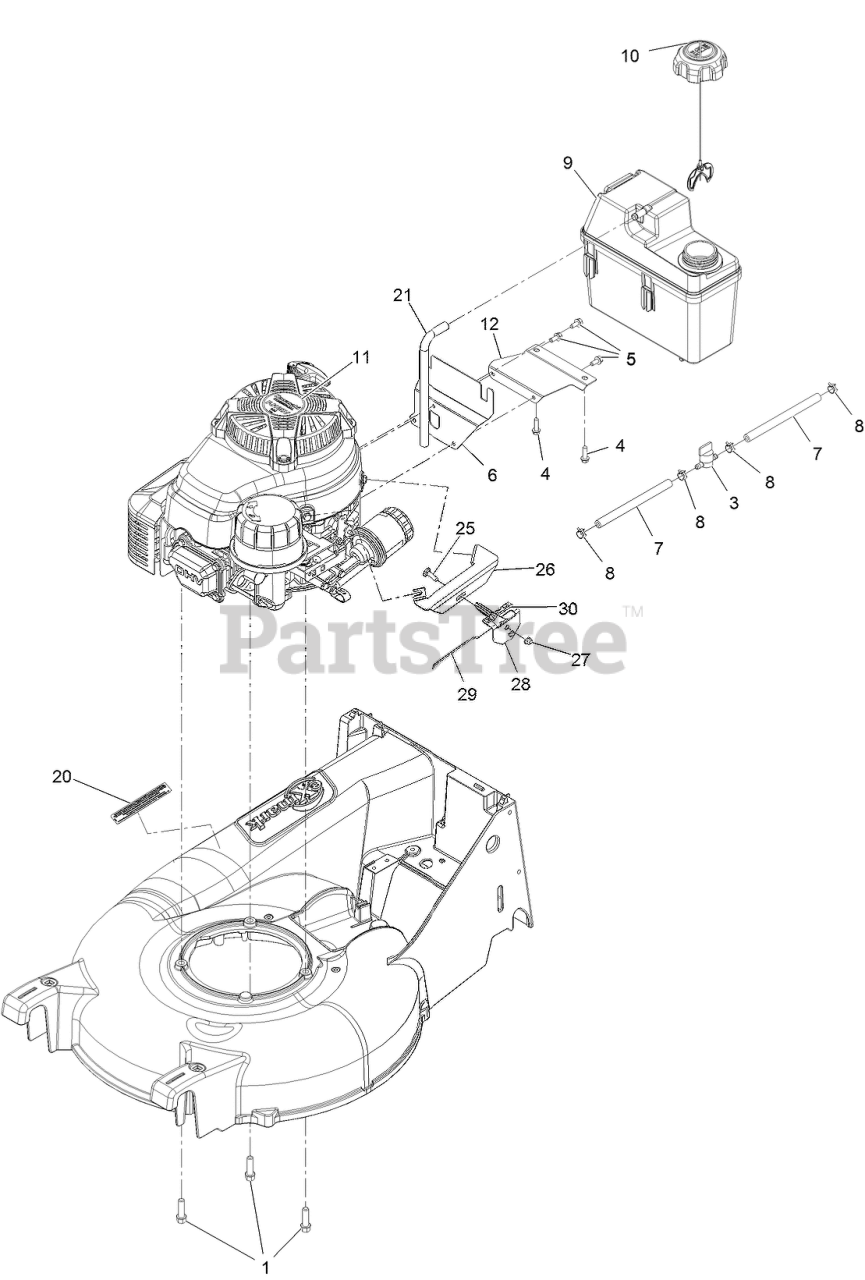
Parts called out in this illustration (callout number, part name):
1	SCREW-TAPTITE
3	VALVE-FUEL
4	SCREW-HWH
5	SCREW-HWH
6	BRACKET-TANK, MOUNTING
7	HOSE-FUEL
8	CLAMP-HOSE
9	TANK-FUEL
10	CAP-FUEL
12	BRACKET-TANK, SUPPORT
20	DECAL-ARRESTOR, SPARK
21	HOSE-VENT, CANISTER
25	SCREW-CARR
26	BRACKET-MOUNT, THROTTLE
28	CONTROL-THROTTLE
29	WIRE-CONTROL
30	DECAL-THROTTLE, CHOKE
